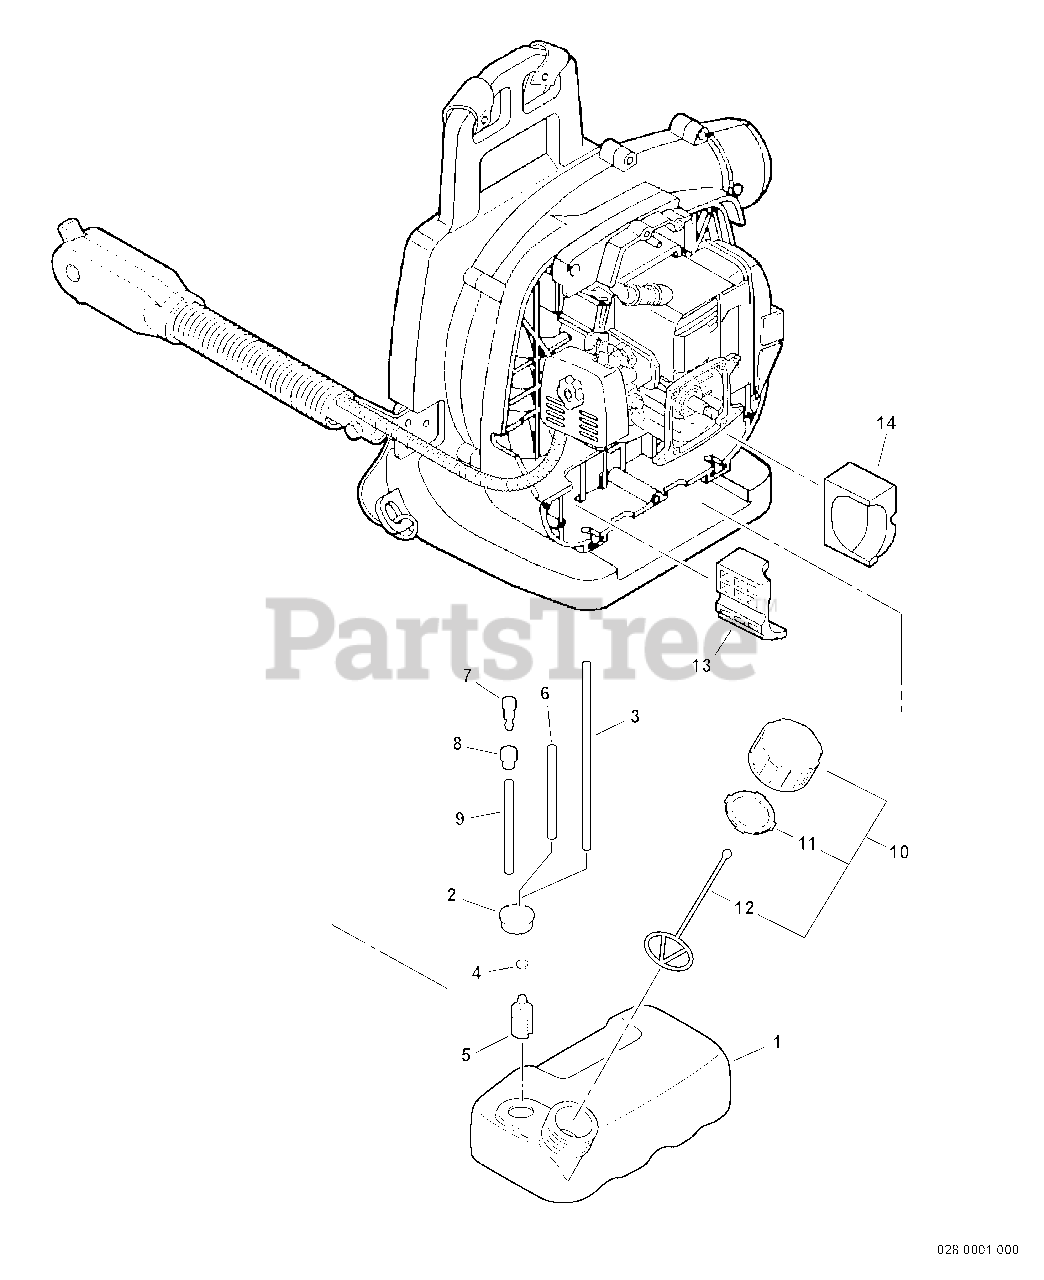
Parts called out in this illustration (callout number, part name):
1	TANK, FUEL
2	GROMMET, FUEL
3	PIPE, FUEL 3×6×200
4	CLIP Ø6.5 MM
5	FILTER, FUEL
6	PIPE, FUEL 3×6×100
7	VENT ASSY
8	HOLDER, VENT
9	PIPE, FUEL 3×6×100
10	CAP ASSY, FUEL
11	GASKET, FUEL CAP
12	CONNECTOR, CAP L= 100 MM
13	CUSHION
14	CUSHION
